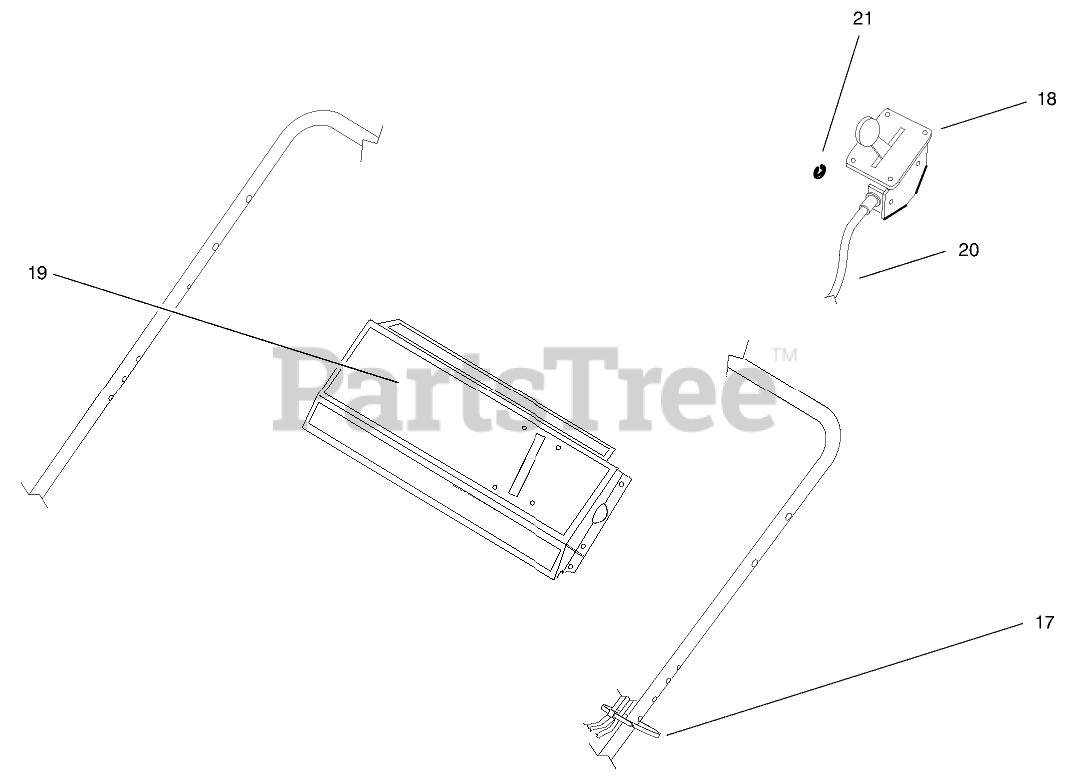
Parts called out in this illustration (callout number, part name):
17	TIE-CABLE
18	CONTROL-THROTTLE
20	CABLE-THROTTLE
21	E-RING
